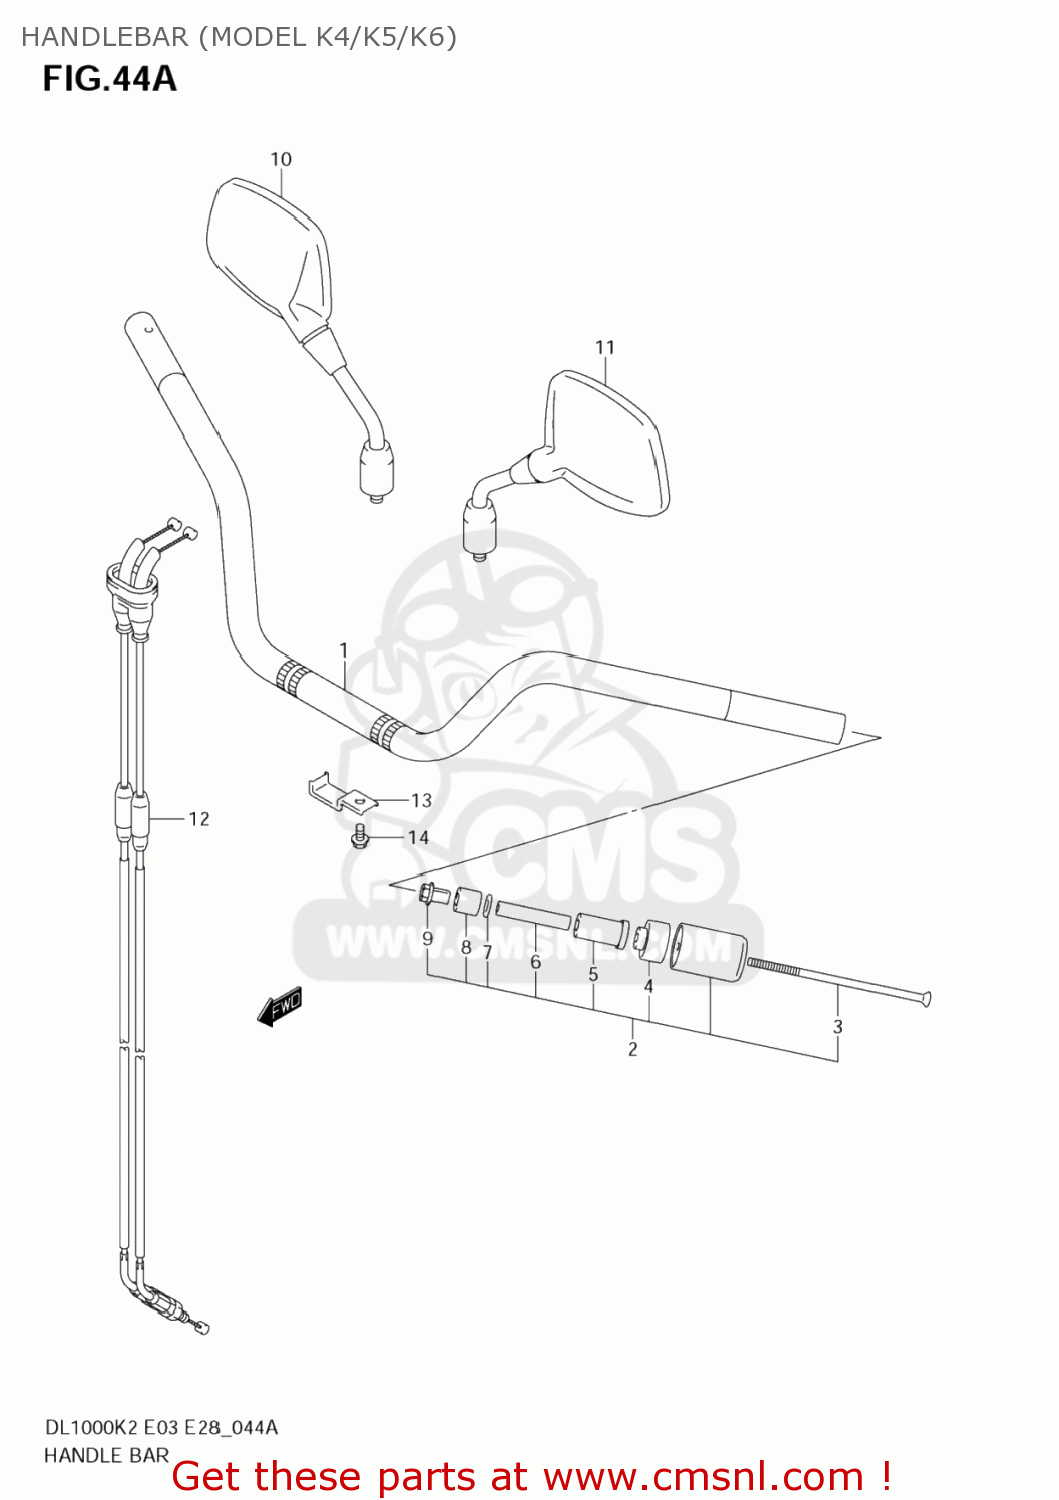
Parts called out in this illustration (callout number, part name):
1	HANDLEBAR
2	BALANCER,HANDL
3	SCREW(6X140)
4	SPACER,KNUCKLE COVER
5	EXPANDER
6	SPACER,EXPANDER
7	WASHER(6.5X16X1.6)
8	EXPANDER,HANDLE BALANCER
9	NUT,HANDLE BAL
10	MIRROR ASSY,RH
11	MIRROR ASSY,LH
12	CABLE ASSY,THR
13	GUIDE,THROTTLE CABLE
14	BOLT
